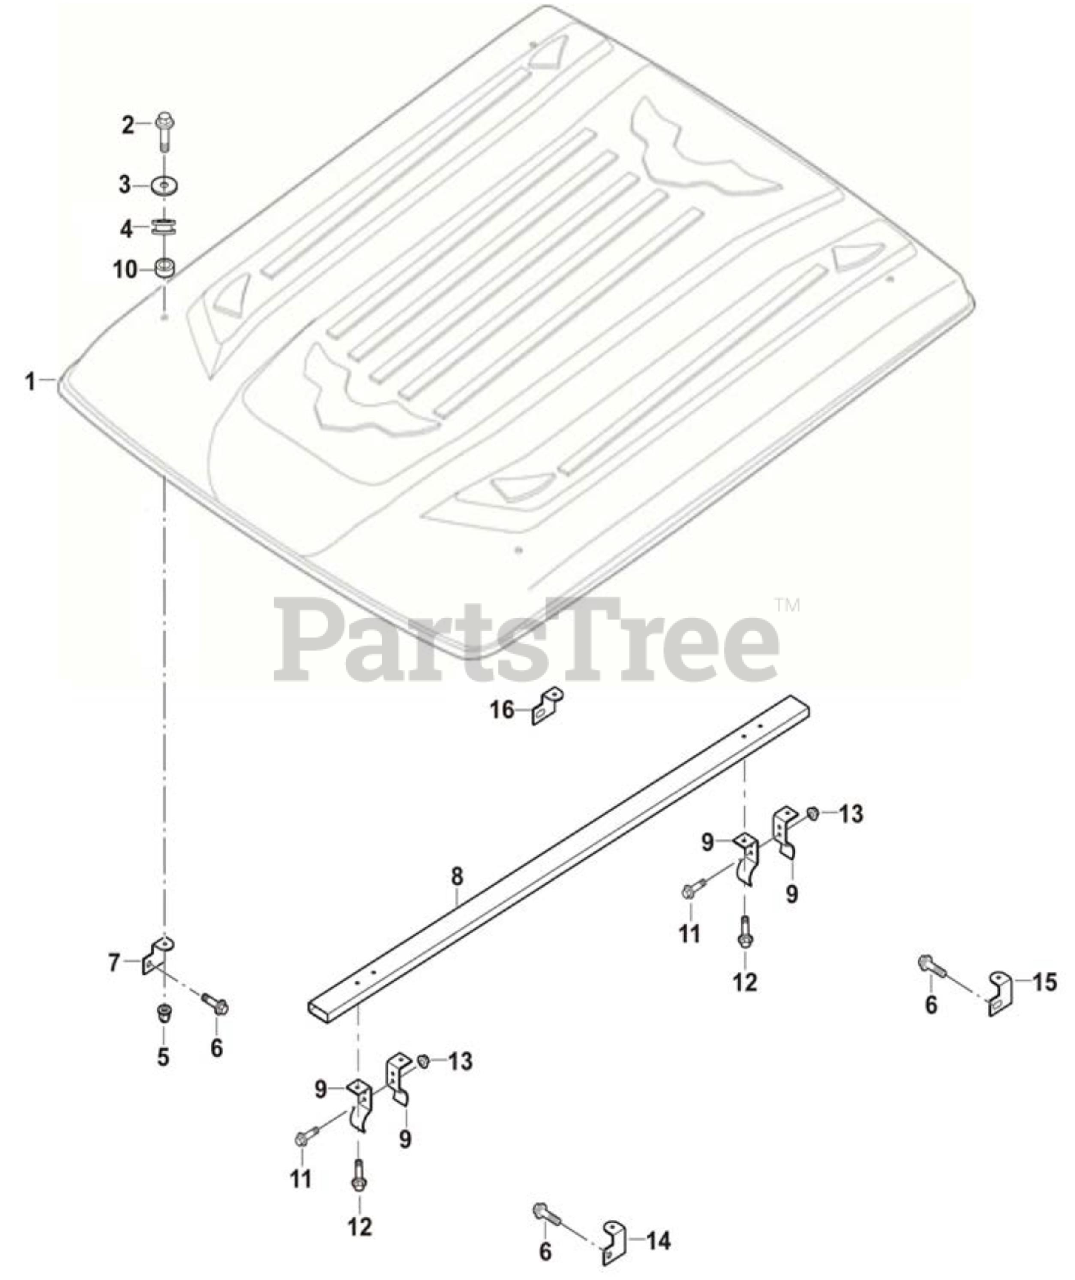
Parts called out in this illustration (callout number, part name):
2	Hexagon Flange Bolt M6X25
3	Flat Washer 7X30X3
4	Shock pad,card slot 8X6.5
5	Cap Nut M6
6	Hexagon Flange bolt M10X1.25X20
7	Mounting Lug II, Platfond
8	damping article II,Platfond
9	Mounting Lug III, Platfond
10	Round Bushing 7X9X10
11	Hexagon Flange Bolt M6X16
12	Hexagon Flange BoltM6X20
13	Hexagon Flange Locked Nut M6
14	Mounting Lug I, Platfond
15	Mounting Lug III, Platfond
16	Mounting Lug IV, Platfond
